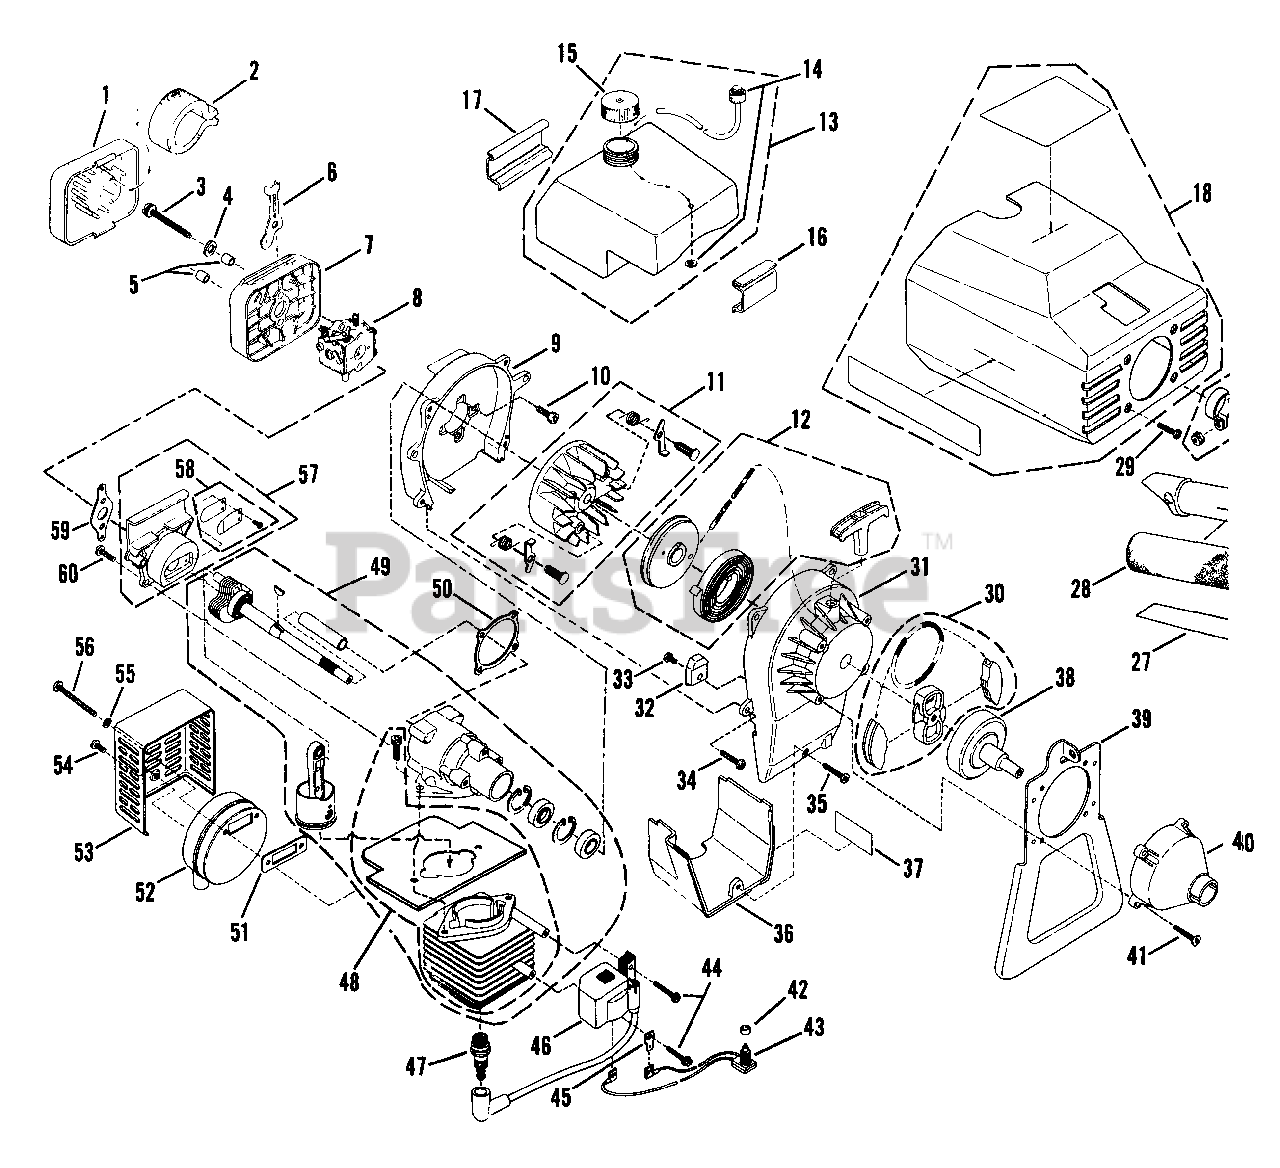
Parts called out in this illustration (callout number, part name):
1	COVER, Air Cleaner
2	FILTER, Air Cleaner
3	SCREW, Carburetor Mounting
4	WASHER, Spring, Choke Base
5	SLEEVE, Choke Base
6	LEVER, Choke
7	BASE, Choke
8	CARBURETOR, Assembly
9	HOUSING, Flywheel
10	SCREW, Flywheel Housing
11	FLYWHEEL ASSEMBLY
12	RECOIL STARTER ASSEMBLY
13	FUEL TANK ASSEMBLY
14	FUEL LINE, Assembly
15	CAP, Fuel Tank (Vented)
16	PAD, Fuel Tank (Front Mtg.)
17	PAD, Fuel Tank(Rear Mtg.)
18	HOUSING ASS'Y, Engine & Decals
19	CLAMP, Housing Assembly
27	STRIP, Adhesive
28	GRIP, Handle
29	SCREW, 010-32x1 1/4"
30	CLUTCH SHOE, Assembly
31	HOUSING, Starter
32	RETAINER, Pulley
33	SCREW, Pulley Retainer
34	SCREW, Starter Housing
35	SCREW, Housing
36	SHROUD, Extension
37	DECAL, Serial No.
38	DRUM, Clutch
39	STAND, Engine
40	COVER, Clutch
41	SCREW, Cover #10x1"
42	CAP, Switch
44	SCREW, Module
45	TAB, Ground
46	MODULE ASSEMBLY
47	SPARK PLUG
48	CYLINDER BLOCK
49	SHORT BLOCK ASSEMBLY
50	GASKET, Carburetor Mtg.
51	GASKET, Exhaust
52	MUFFLER
53	SHIELD, Muffler
54	BOLT, Muffler Mtg. (Short)
55	WASHER, Muffler Mtg.
56	BOLT, Muffler Mtg.
57	ASSEMBLY, Carburetor Mtg. & Reed
58	REED ASSEMBLY
59	GASKET, Carburetor
60	SCREW, Carburetor Base
